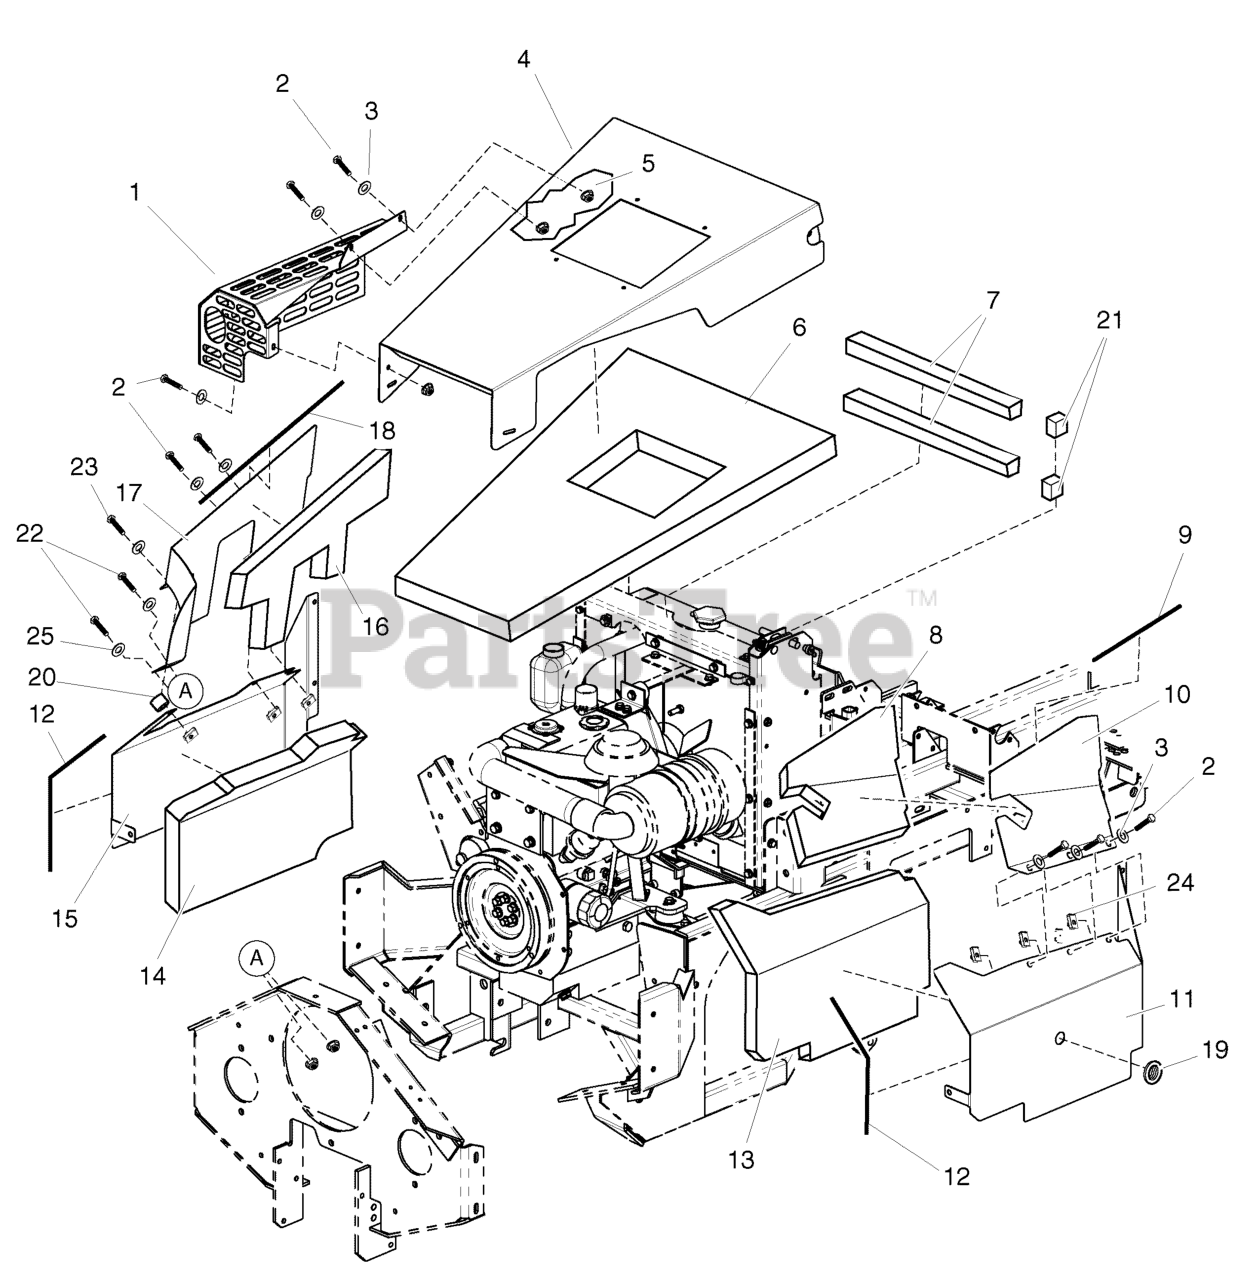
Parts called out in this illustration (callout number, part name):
1	WELD MUFFLER GUARD - RED
2	HHCS, 1/4-20 X 0.625, GR5, ZINC/CLEAR
3	WASHER, 1/4 SAE
4	WELD , HOOD IS4500Z - RED
5	NUT, 1/4-20 HEX NYLOCK FLANGE
6	SOUND BAFFLE, FOAM HOOD
7	FOAM, 3/4" X 1", 18" LONG
8	SOUND BAFFLE, FOAM UPPER - RH
9	BLACK SOFTONE Q-TRIM 7" LONG
10	SOUND BAFFLE, UPPER - RH - RED
11	SOUND BAFFLE, LOWER - RH - RED
12	BLACK SOFTONE Q-TRIM 11" LONG
13	SOUND BAFFLE, FOAM LOWER - RH
14	SOUND BAFFLE, FOAM LOWER - LH
15	SOUND BAFFLE, LOWER - LH - RED
16	SOUND BAFFLE, FOAM UPPER - LH
17	SOUND BAFFLE, UPPER - LH - RED
18	BLACK SOFTONE Q-TRIM 18.75" LONG
19	GROMMET, 3/4"
20	SPACER, .39 X 1.00 X .25
21	FOAM, 3/4" X 1" X 1" LONG
22	BOLT, 5/16-18 X 1"
23	BOLT, 1/4-20 X 1" GD5 CZ
24	BODY CLIP, 1/4-20
25	WASHER, 5/16" SAE
